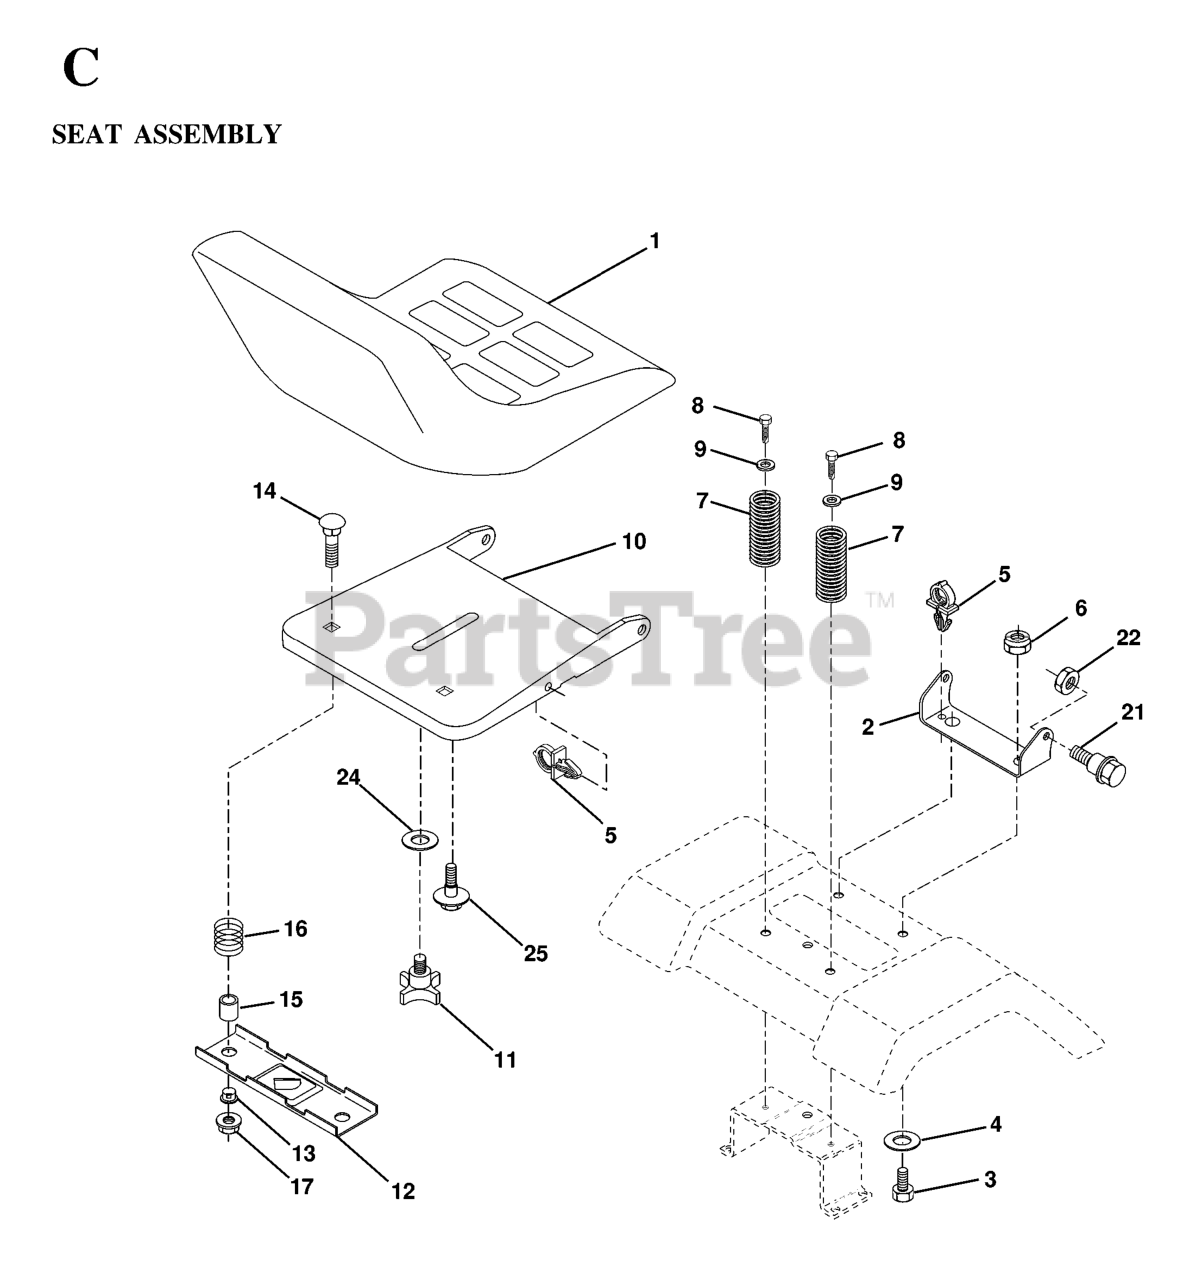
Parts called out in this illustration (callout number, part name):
1	SEAT, GRAY
2	SEAT PIVOT BRKT
3	BOLT
6	NUT
7	SPRING COMPRESSION
8	SCREW GTV
9	WASHER
10	SEAT PAN
11	KNOB 1/2" YT
12	BRKT SWITCH
14	Bolt Rdhd. Sht. Nk 1/4-20 x 1-3/8
15	SPACER SPLIT 28X.96
17	NUT T
21	BOLT SHOULDER 5/16-18
22	NUT.71038.31-18.HEX.NYLOCK
25	BOLT,SHOULD
